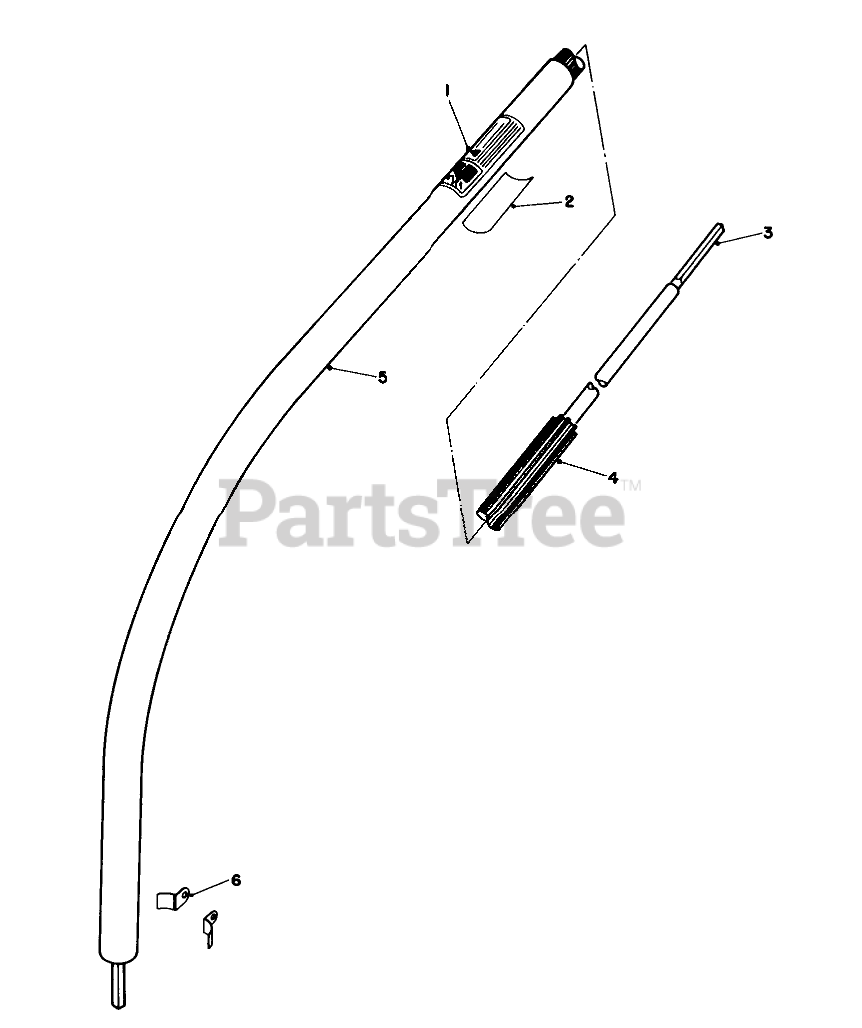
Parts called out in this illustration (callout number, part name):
1	Decal
2	REP. SERIAL PLT
3	Shaft-Flex Assembly (Incl. Ref. #4)
4	Casing-Flex Shaft
5	Tube-Lower Shaft Assembly (Incl. Ref. #1)
6	LOWER TUBE RETAINER
